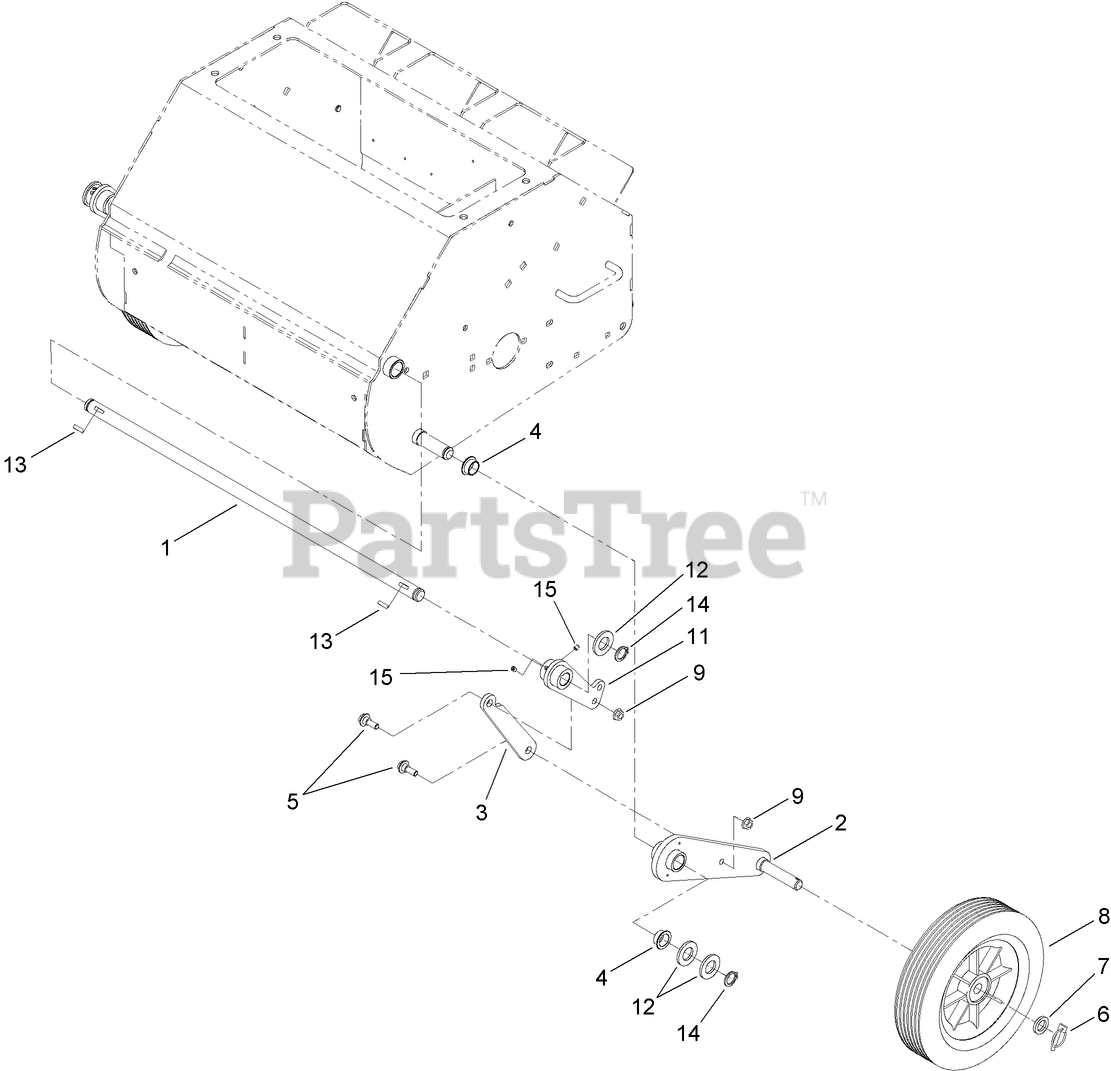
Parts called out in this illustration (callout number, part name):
1	SHAFT-PIVOT
2	ARM-WHEEL
3	LINK-CONNECTING
4	BUSHING-BRONZE
5	SCREW-SHOULDER
6	PIN-KLIK
7	SPACER-BEARING
8	WHEEL-TRANSPORT 10"
9	NUT-HF
11	ARM-LIFT
12	WASHER-FLAT
13	KEY-WOODRUFF
14	RING-RETAINING
15	SCREW-SET
